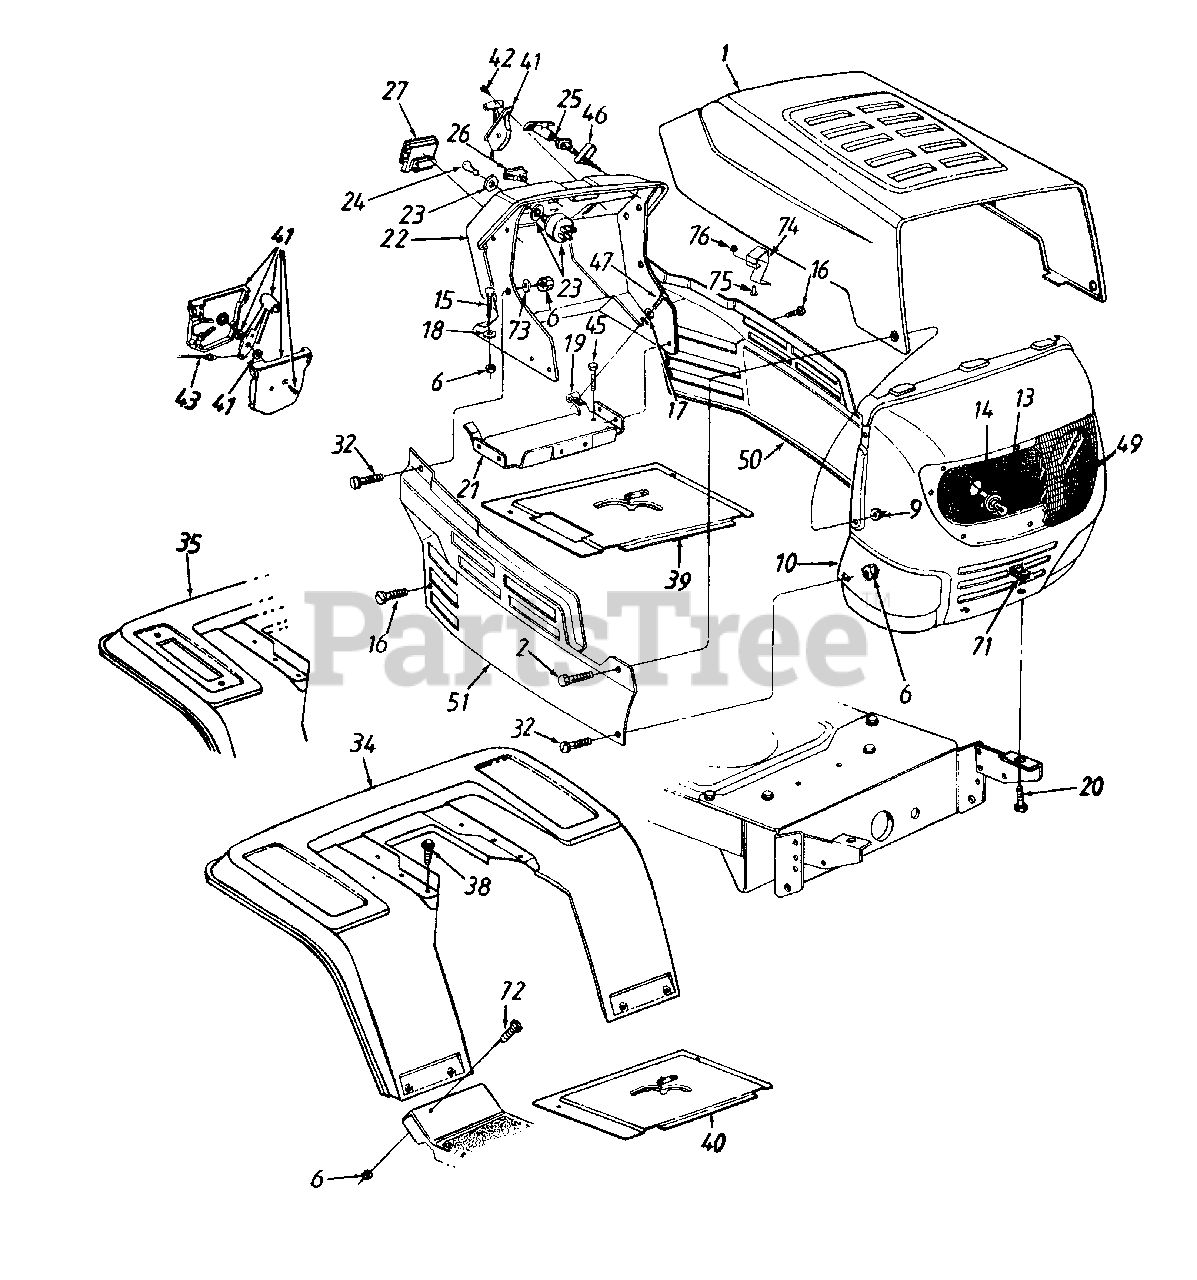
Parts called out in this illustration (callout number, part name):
6	Hex Sems Nut 1/4-20 Thd.
9	Flange L-Nut 1/4-20 Thd.
13	Lamp
14	Socket
15	Carriage Bolt 1/4-20 x .75" Lg.
16	Hex Wash. Hd. TT-Tap Scr. 1/4-20 x .5" Lg.
17	Fl-Wash. .281" I.D. x .73" O.D.
18	Bolt Retainer 1/4" I.D.
19	Speed Nut 1/4-20 Thd.
20	Hex Bolt 5/16-18 x .75" Lg.
23	Ignition Switch
24	Ignition Key
25	Choke Control 23" Lg.
26	Light Switch
27	Ammeter
32	Pan Hd. Scr. 1/4-20 x .75" Lg.
41	Throttle Box Ass'y.
42	Truss Mach. AB-Tap Scr.#10 x .5" Lg.
43	Throttle Control Wire 18.5" Lg.
45	Hex Wash. Hd. B-Tap Scr. 5/16-18 x .5" Lg.
46	Choke Retainer
47	Hex TT-Tap Scr. 1/4-20 x .75"Lg.
49	Lens
73	Fl-Wash. .283" I.D. x .75" O.D.
74	Hood Latch
75	Truss Mach. Scr. #10-24 x .5" Lg.
76	Hex Sems Nut 10-24 Thd.
